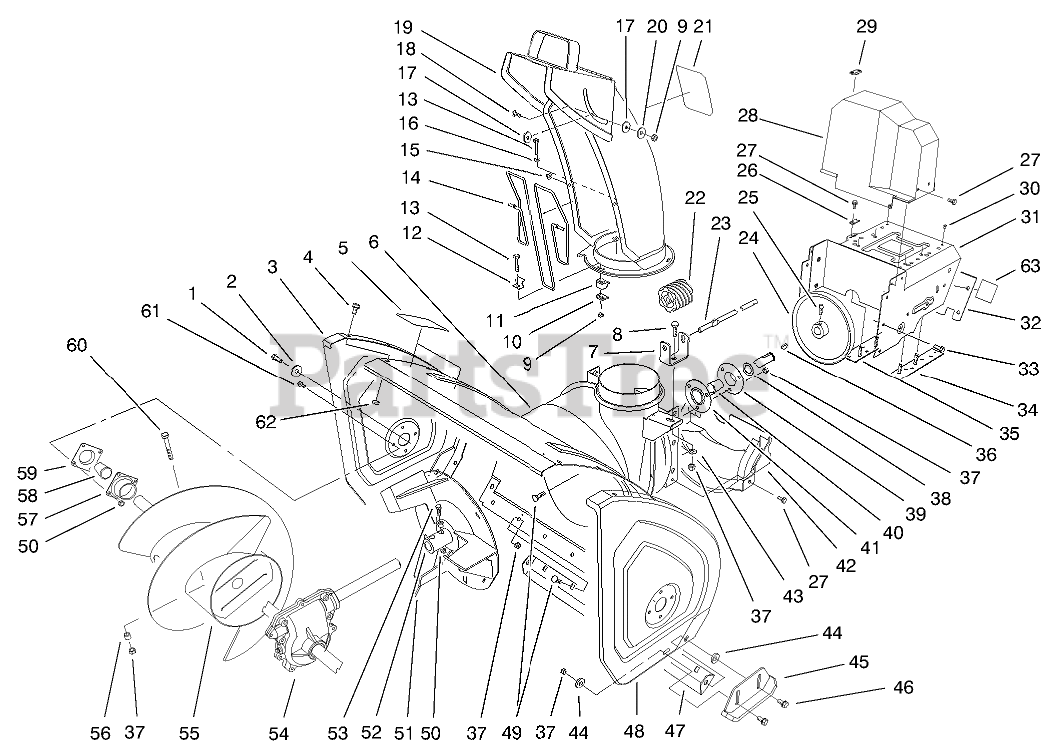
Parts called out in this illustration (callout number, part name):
1	SCREW-HH
2	WASHER
3	PLATE-SIDE, RH
4	SCREW-HHF
6	Auger Housing ASM (only on: 38079)
6	Auger Housing ASM (only on: 38547)
6:2	Decal-Warning, Auger (only on: 38547)
6:2	Decal-Warning, Auger (only on: 38079)
7	BRACKET-WORM, CHUTE
8	BOLT-CARR
9	NUT-LOCK, NI
10	PLATE-RETAINER, CHUTE
11	RETAINER-CHUTE
12	CLIP-GUARD, CHUTE
13	SCREW-HSH
14	GUARD-CHUTE
15	NUT-PUSH
16	WASHER-FLAT
17	WASHER-PLASTIC
19	Chute (only on: 38547)
19	Chute (only on: 38079)
19:2	Decal-Danger Discharge (only on: 38079)
19:2	Decal-Danger (only on: 38547)
20	WASHER-FLAT
22	GEAR-WORM
23	ROD-CHUTE, LOWER
24	PULLEY-IMPELLER
25	SCREW-SET, SQH
26	RETAINER-CABLE
27	SCREW-HWH
28	COVER-BELT, UPPER
29	COVER-CABLE
30	RIVET-POP
31	Engine Frame ASM (only on: 38547)
31	Engine Frame ASM (only on: 38079)
31:2	Decal-Warning (only on: 38547)
31:2	Decal-Adjustment (only on: 38079)
32	COVER-FRAME, ENGINE
33	SCREW-HWHTF
34	LH FRAME PLATE ASM
35	RH FRAME PLATE ASM
36	KEY-WOODRUFF
37	NUT-LOCK, NI
38	WASHER-THRUST
39	FLANGE-CUP, BEARING
40	BEARING-BALL
41	FLANGE-CUP, BEARING
42	COVER-BELT, LOWER
43	WASHER-PLAIN
44	WASHER
45	SKID ASM
46	SCREW-HHF
47	SCRAPER BLADE ASM
48	PLATE-SIDE, LH
49	SCREW-CARR
50	NUT-LOCK, NI
51	BLADE IMPELLER ASM
52	SPACER
53	SCREW-HHF
54	AUGER GEARCASE ASM
55	RH AUGER ASM
56	SPACER-HUB, AUGER
57	BEARING-FLANGE, FRONT
58	BEARING
59	BEARING-FLANGE, REAR
60	SCREW-HH
61	SCREW-HH
62	NUT-LOCK, NI
63	Decal (only on: 38547)
